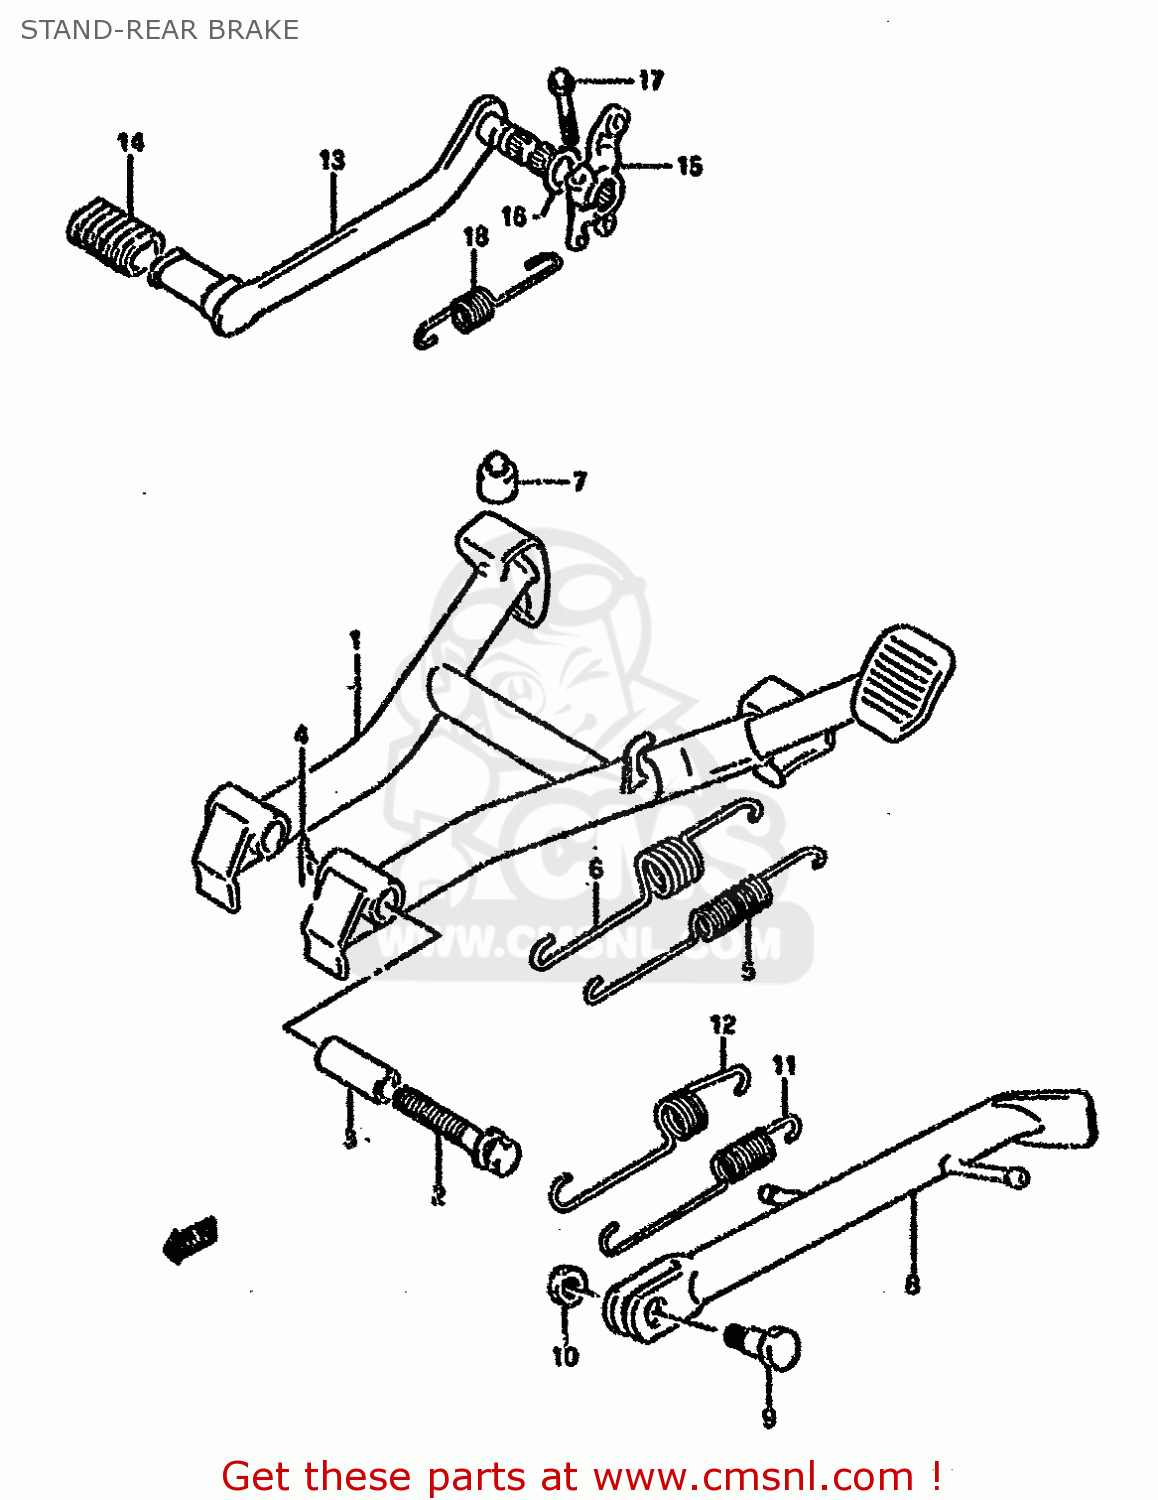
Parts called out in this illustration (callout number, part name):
1	STAND,CTR
2	BOLT
3	SPACER(10X16X38.8)
4	CLIP
5	SPRING
6	SPRING OUTER
7	CUSHION
8	STAND,PROP(BLACK)
9	BOLT L:30
10	NUT
11	SPRING
12	SPRING
13	PEDAL,BRAKE
14	RUBBER,PEDAL
15	ARM,BRAKE ROD
16	WASHER
17	BOLT
18	SPRING
